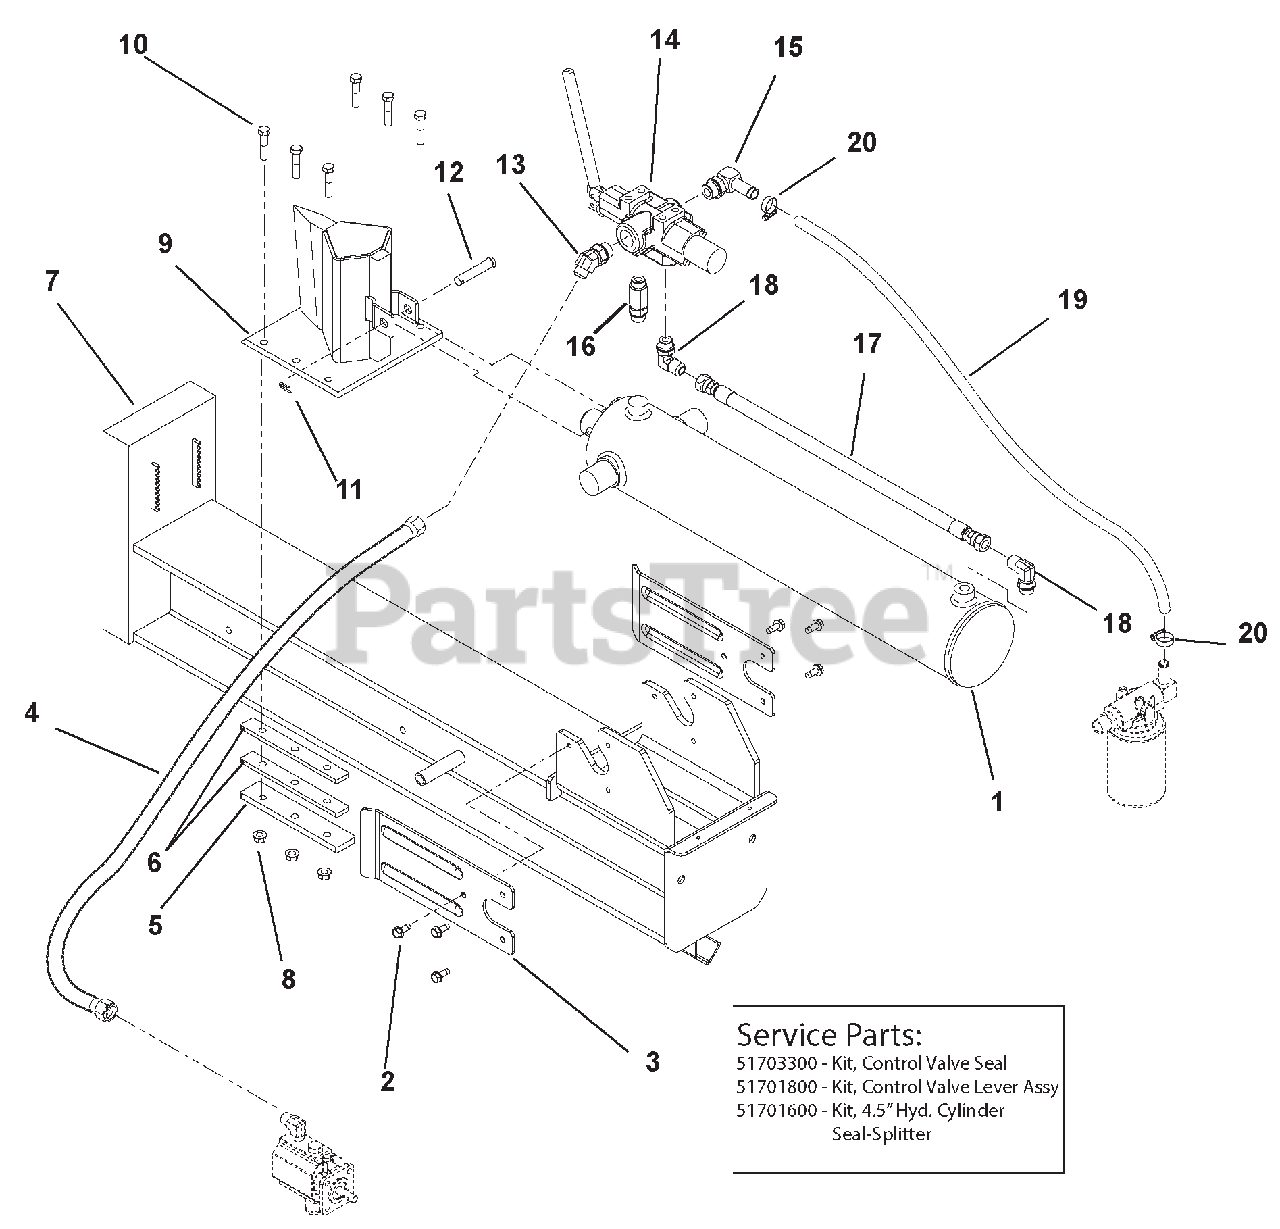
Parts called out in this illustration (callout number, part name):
1	CYLINDER,4.5 W/DECALS
1	KIT,4.5" HYD CYL SEAL-SPLITTER
2	@SCR-TAP .31-18X.75 HWH TR YWZ
3	PLATE,STRIPPER
4	HOSE, ASM - 46"
5	RETAINER,WEDGE
6	SPACER,WEDGE
7	WLDMT, SPLITTER BEAM
8	@NUT-LK-TOP-FLG .38-16 YWZC
9	WEDGE
10	@BLT-HEX .38-16X1.75 GR5 YWZC
11	CLIP, SPRING
12	PIN-CLEV .494X2.50 BRIGHT ZINC
13	FTG,HYD 6802-8-10
14	VALVE CONTROL-SPLITTER
14	KIT,CONTROL VALVE SEAL
14	KIT,CONTROL VALVE LEVER ASSY
15	FTG,HYD 4601-10-10
16	FTG,HYD 6403-NWO-8-8-L
17	HOSE, HYD - 22"
18	FTG,HYD 6801-8-8
19	HOSE,HYD RETURN 10LOLA X 53"
20	CLAMP,.88 DIA. HOSE
